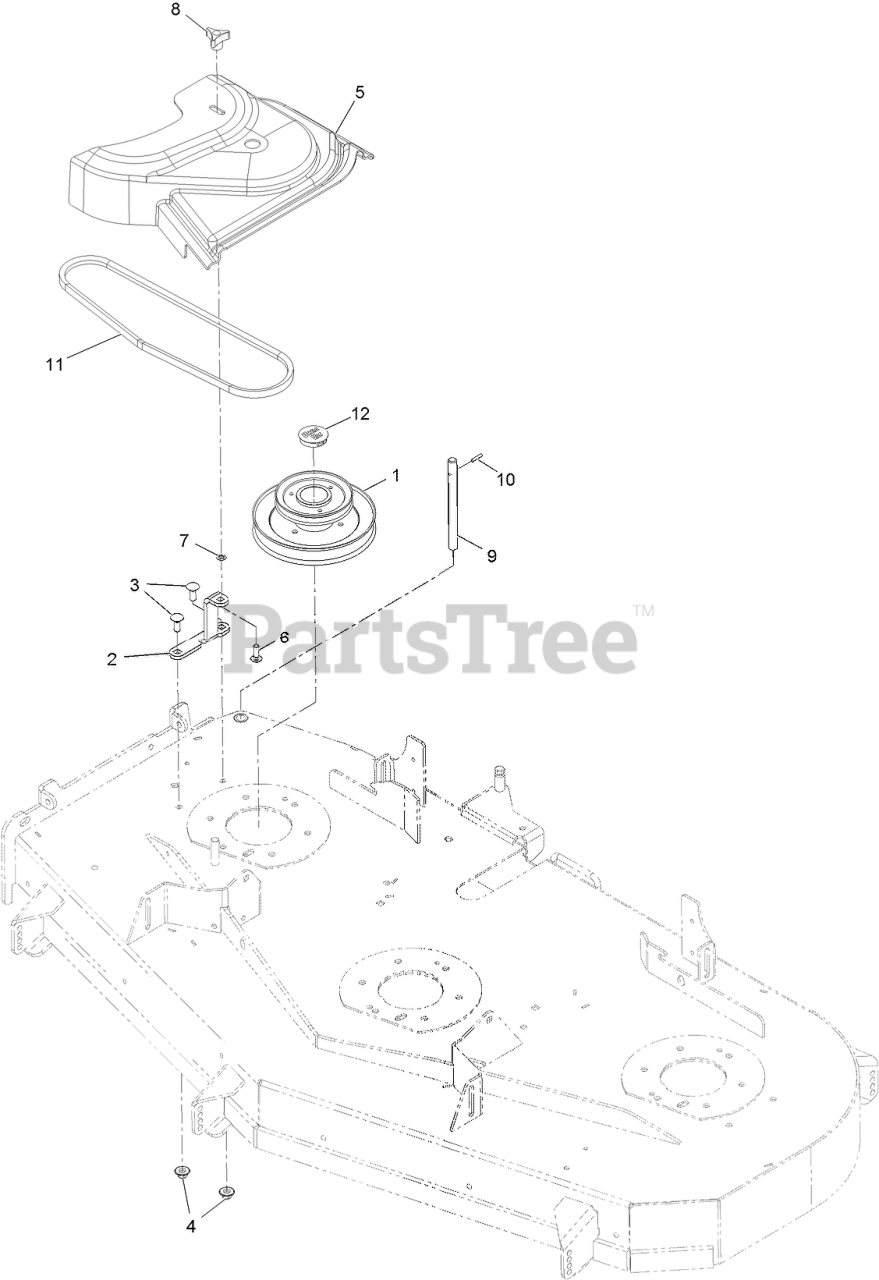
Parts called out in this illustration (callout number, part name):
1	JACKSHFT- UV DRIVE 603
2	BRACKET-BELT COVER
3	BOLT-CARR
4	Nut-Nyloc 3/8-16 Flg
5	COVER-BELT, UV 60 ENTRY
6	BOLT-CARR
7	RING-RETAINING, BOLT
8	KNOB-3 PRONG
9	SHAFT-CATCHER, GRASS
10	PIN-ROLL
11	V-BELT (17569)
12	PLUG, BLACK NYLON 1.75
